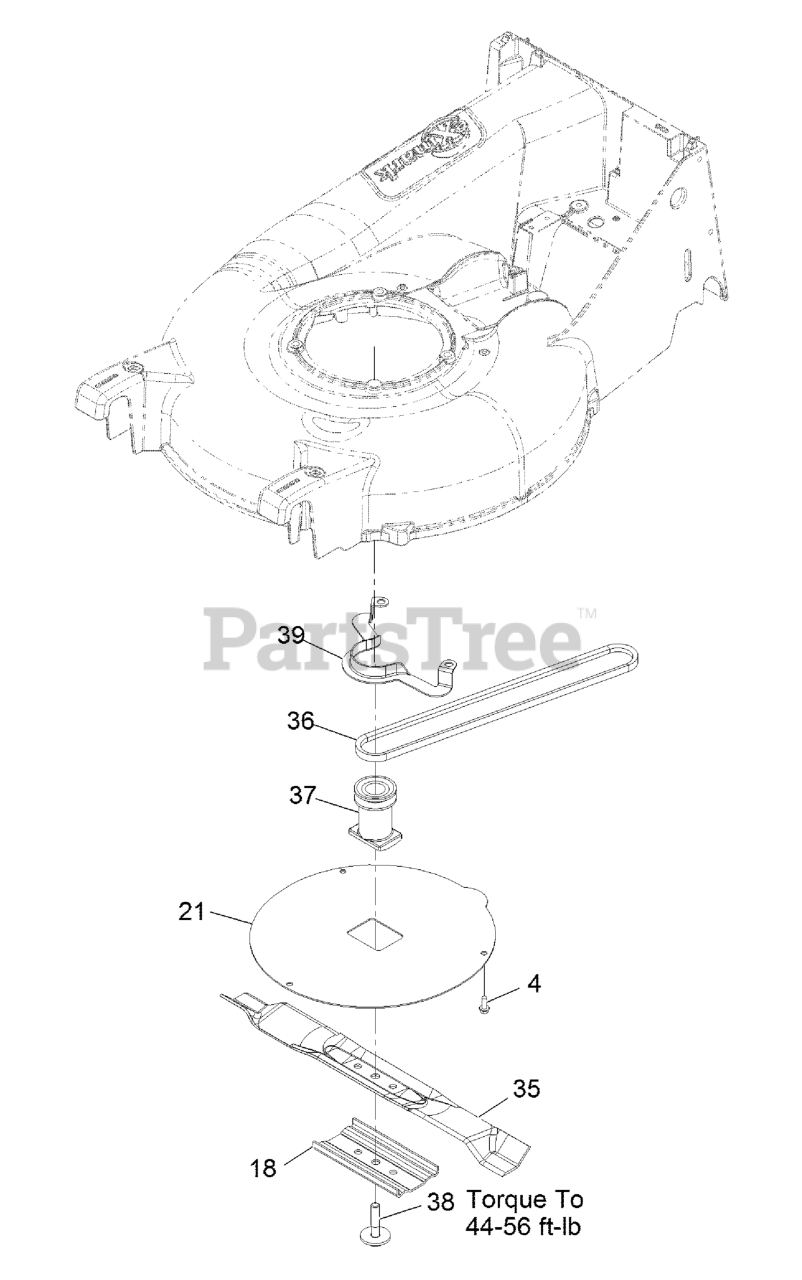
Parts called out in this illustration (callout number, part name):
4	SCREW-HWH
18	SUPPORT-BLADE
35	Blade - Medium Lift, 20.5
36	BELT,3L P21 DRIVE
37	BLADE-ADAPTER
38	BOLT-BLADE, SEM
39	GUIDE-BELT
